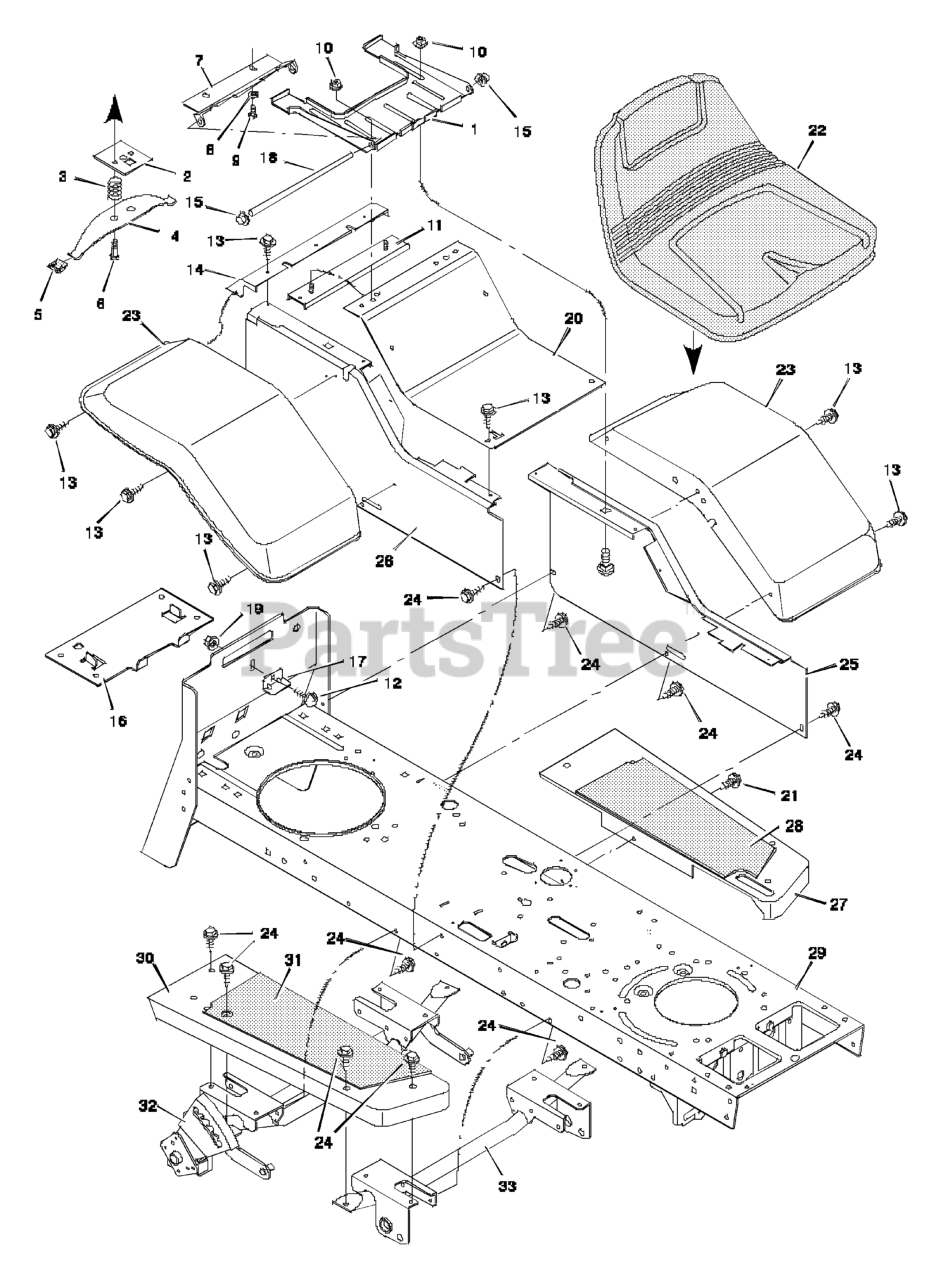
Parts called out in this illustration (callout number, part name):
1	Bracket, Seat
2	Plate Assembly, Switch
3	Spring, Compression
4	Spring, Seat
5	Glide, Spring
6	Bolt, Shoulder
7	Support, Seat
8	Lockwasher
9	Bolt, Hex
10	Locknut, Flange
11	Channel Assembly
12	Bolt, Carriage
14	Insert, Rear
15	Push On Cap
16	Support, Battery
17	Clamp, Battery
18	Rod, Pivot
19	Locknut
20	Panel, Top
21	Fastener, Panel
25	Panel, Left
26	Panel, Right
27	Running Board, Left
28	Mat, Left
29	Frame Channel
30	Running Board, Right
31	Mat, Right
32	Lifter and Support Assembly
33	Support Assembly, Front
